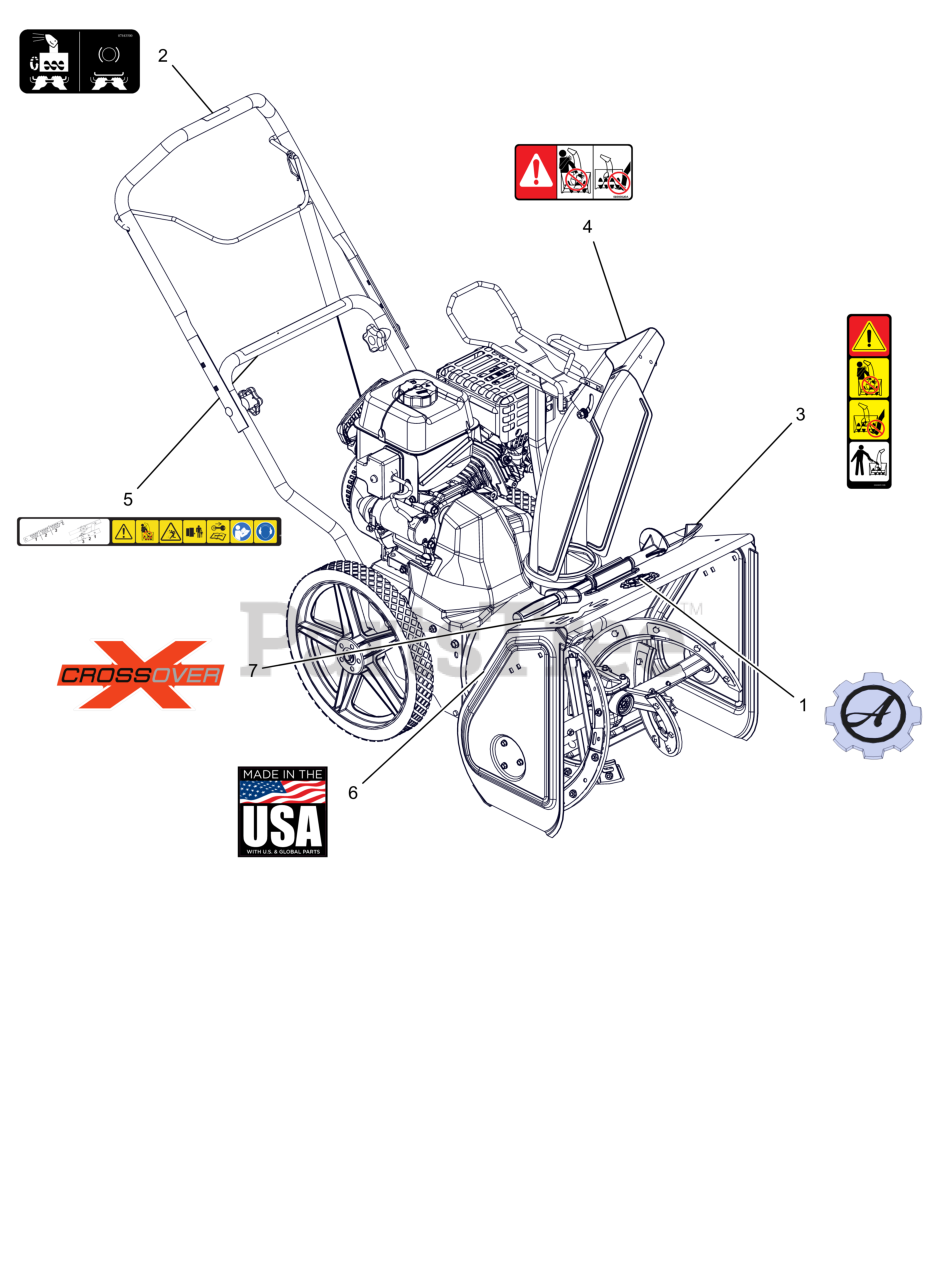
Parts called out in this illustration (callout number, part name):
1	DECAL, ARIENS - GEAR BADGE
2	DECAL-AUGER/IMPELLER BAIL
3	DECAL, DANGER - ROTATING PARTS
4	DECAL, DANGER
5	DECAL, HANDLEBAR WARNING
6	DECAL, MADE IN USA
7	DECAL, CROSSOVER
